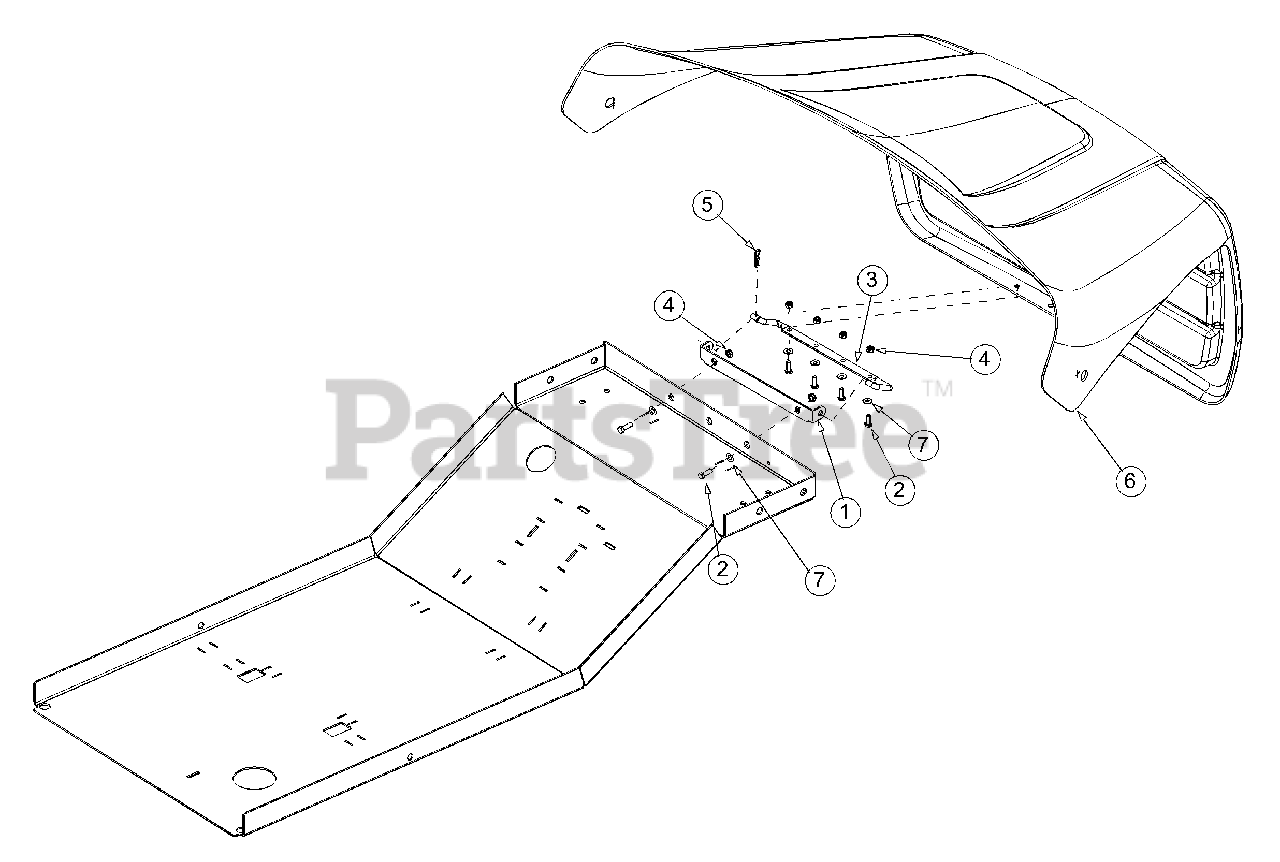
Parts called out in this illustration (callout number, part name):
3	Rod Mounting Hood
4	Nut, Nylon Hex Lock, 1/4-20, Gr8
5	Cotter Pin
6	Panel, Hood
7	Washer, Flat, .271 x .630 x .065
